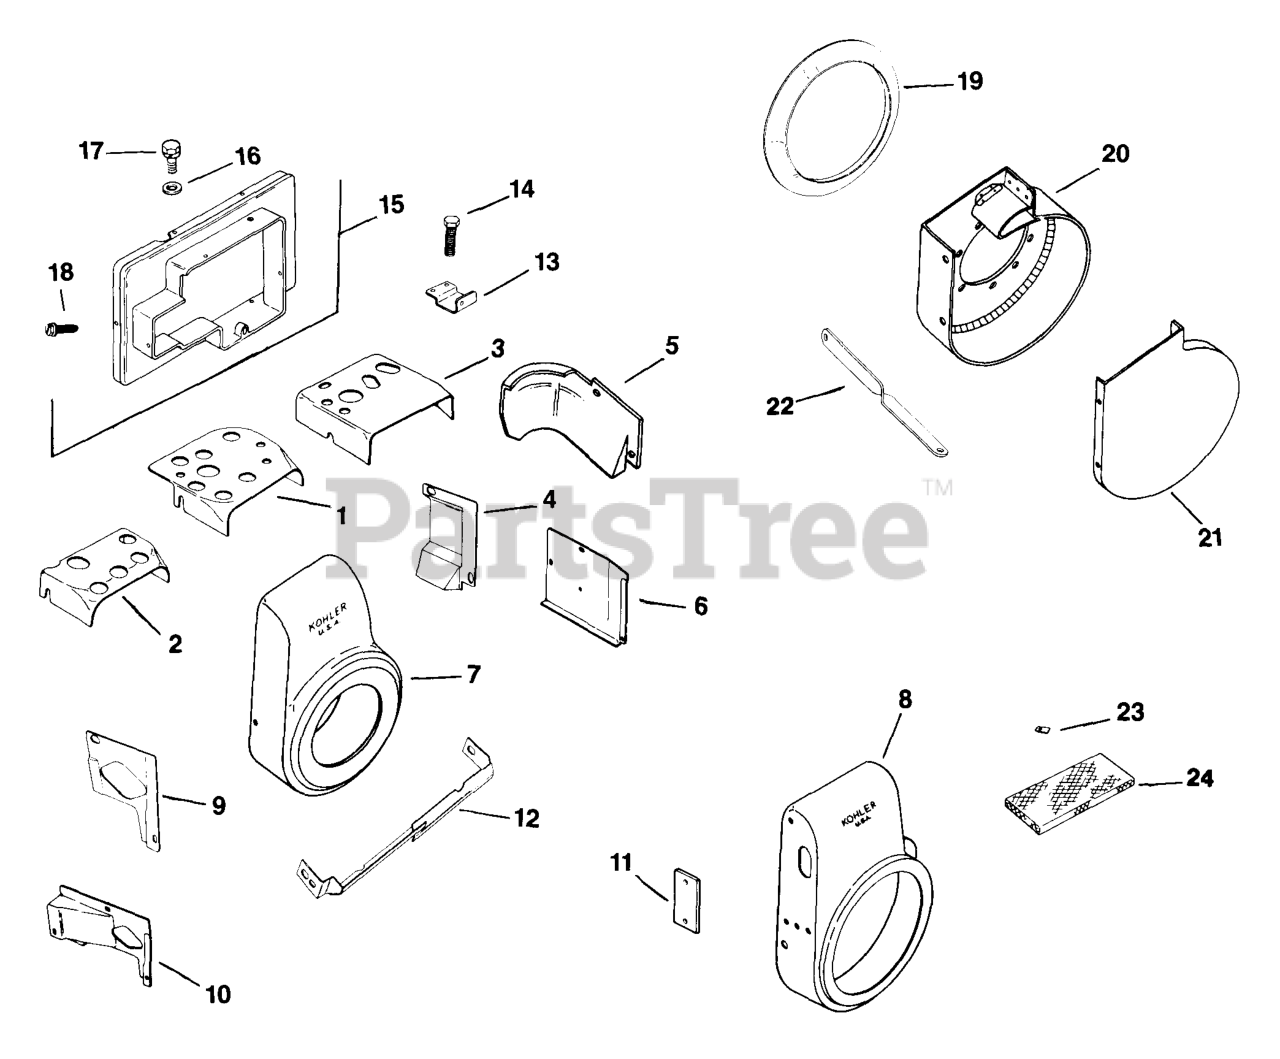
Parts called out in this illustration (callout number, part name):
3	BAFFLE, HEAD
6	BAFFLE, CYLINDER
8	KIT, HOUSING - DISCONTINUED
15	KIT, AIR DUCT
16	WASHER, FLAT 3/16"
17	SCREW, WSH HD TAP #10-32X7/16" USE 25 086 101-S
18	SCREW, WSH HD TAP 1/4-20-5/8" - DISCONTINUED
